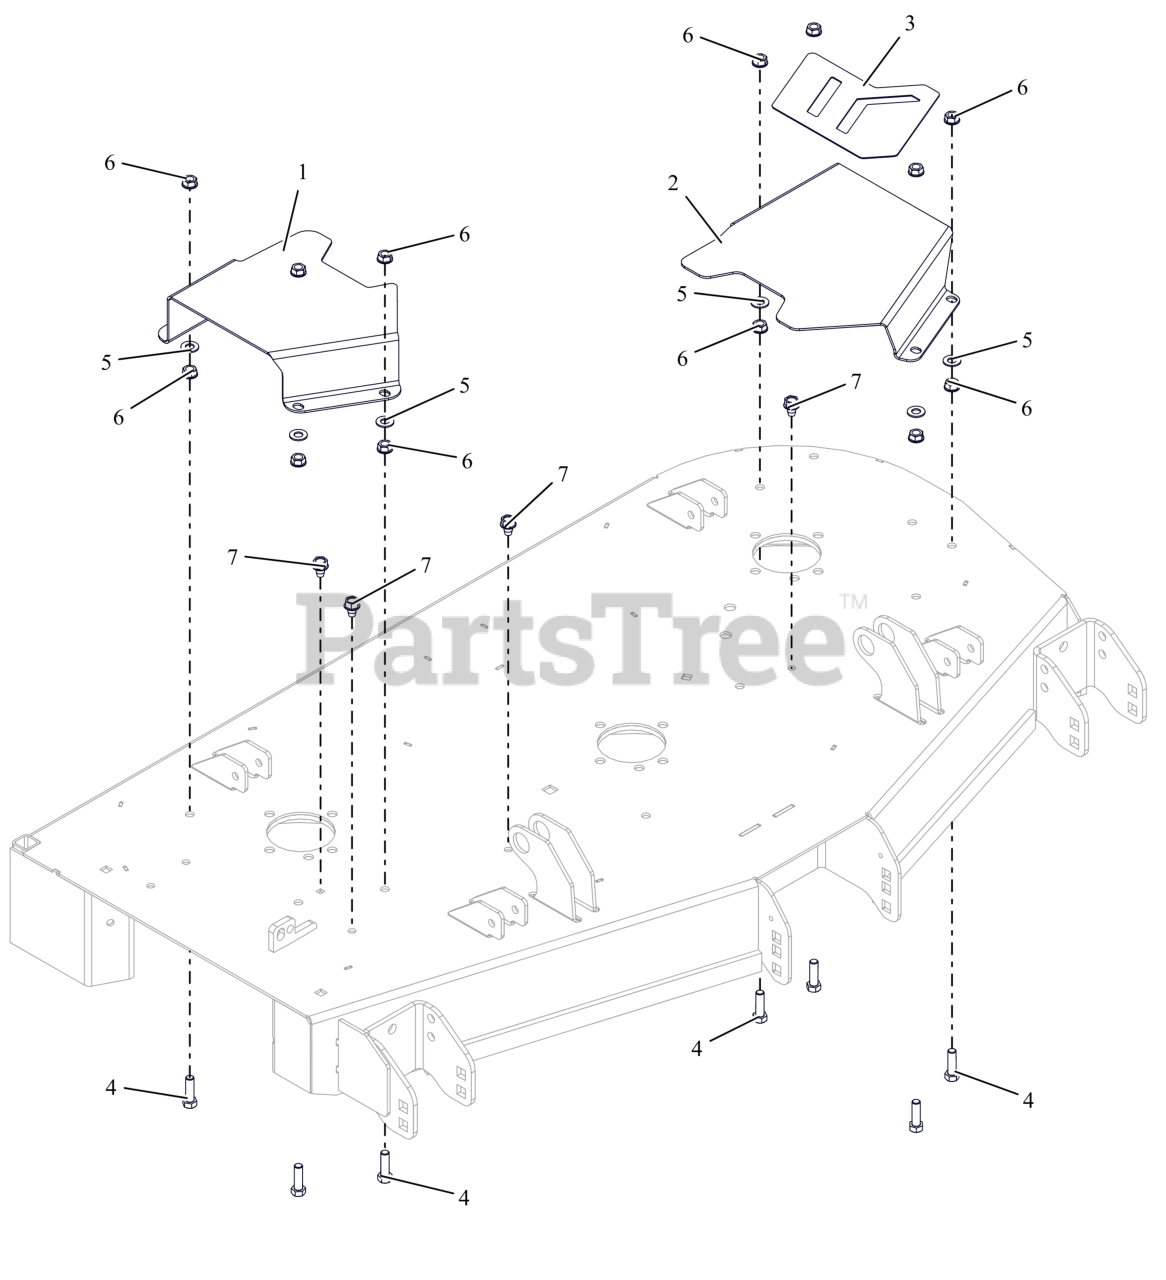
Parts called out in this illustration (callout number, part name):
1	COVER, BELT 48" RIGHT
2	COVER, BELT 48" LEFT
3	GRIP, TAPE 48 BELT COVER
4	BLT, HEX .38-16X1.25 G5 ZCC
5	WSHR,FLT .406X.812X.065 ZCC
6	NUT, SPNLK-FLG .38-16 G5 ZCC
7	SCR,TAP .375-16X.50 HWH TR ZCC
